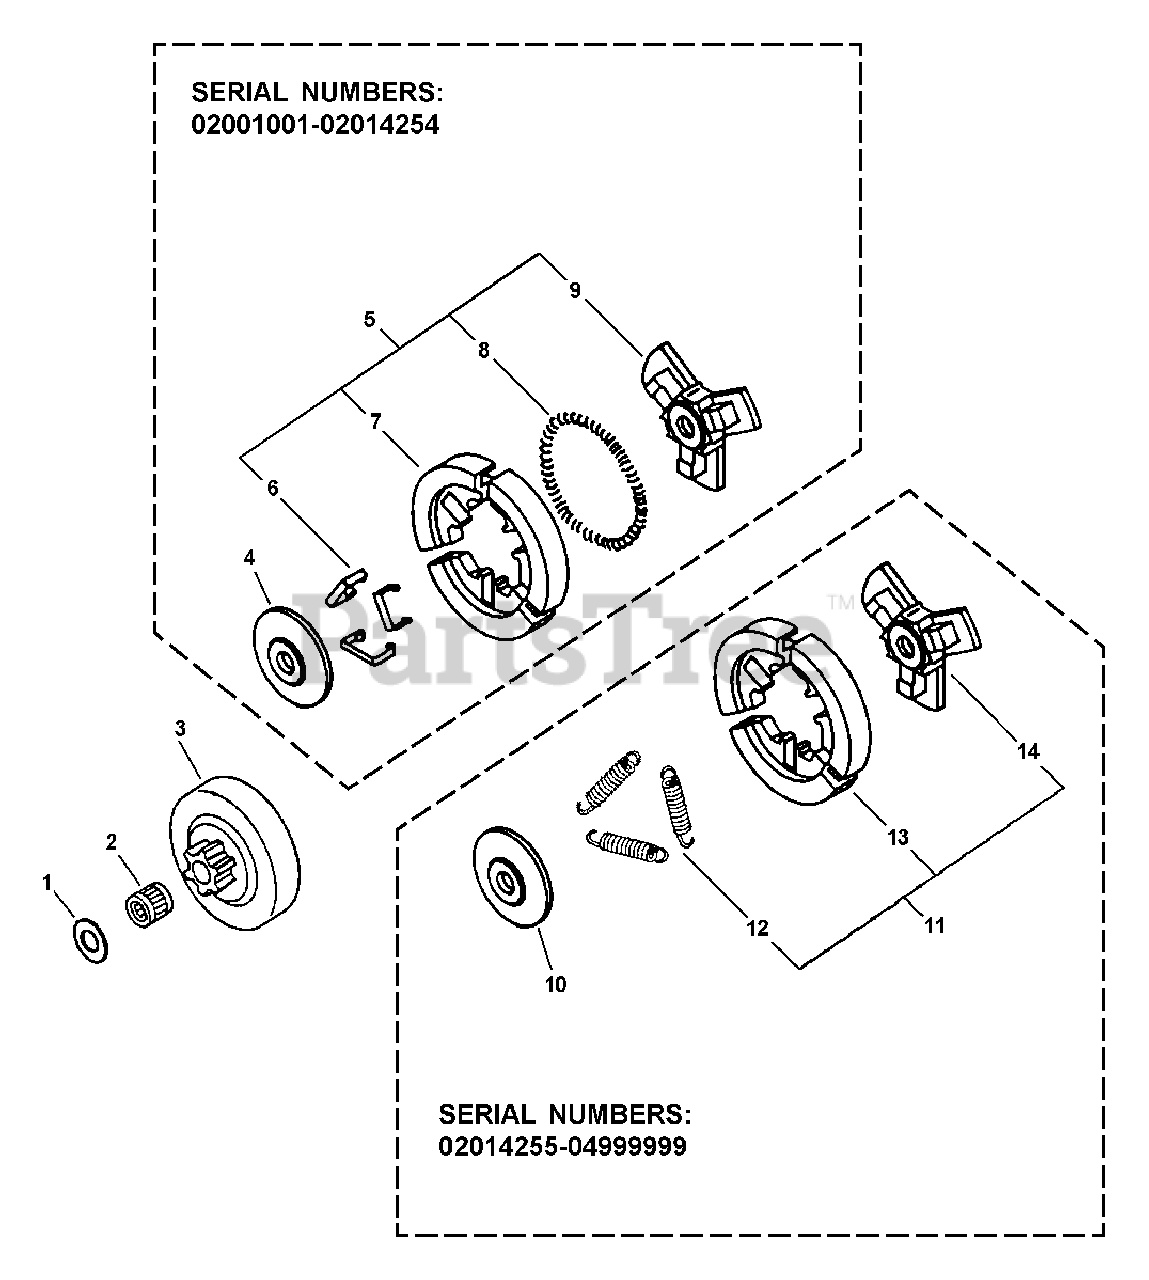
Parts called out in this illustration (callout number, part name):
2	BEARING, NEEDLE
3	DRUM, CLUTCH
4	PLATE, CLUTCH
5	CLUTCH ASSY
6	CLIP, SPRING
7	CLUTCH SHOE SET
8	SPRING, CLUTCH
9	HUB, CLUTCH
10	PLATE, CLUTCH
11	CLUTCH ASSY
12	SPRING, CLUTCH
13	CLUTCH SHOE SET
14	HUB, CLUTCH
